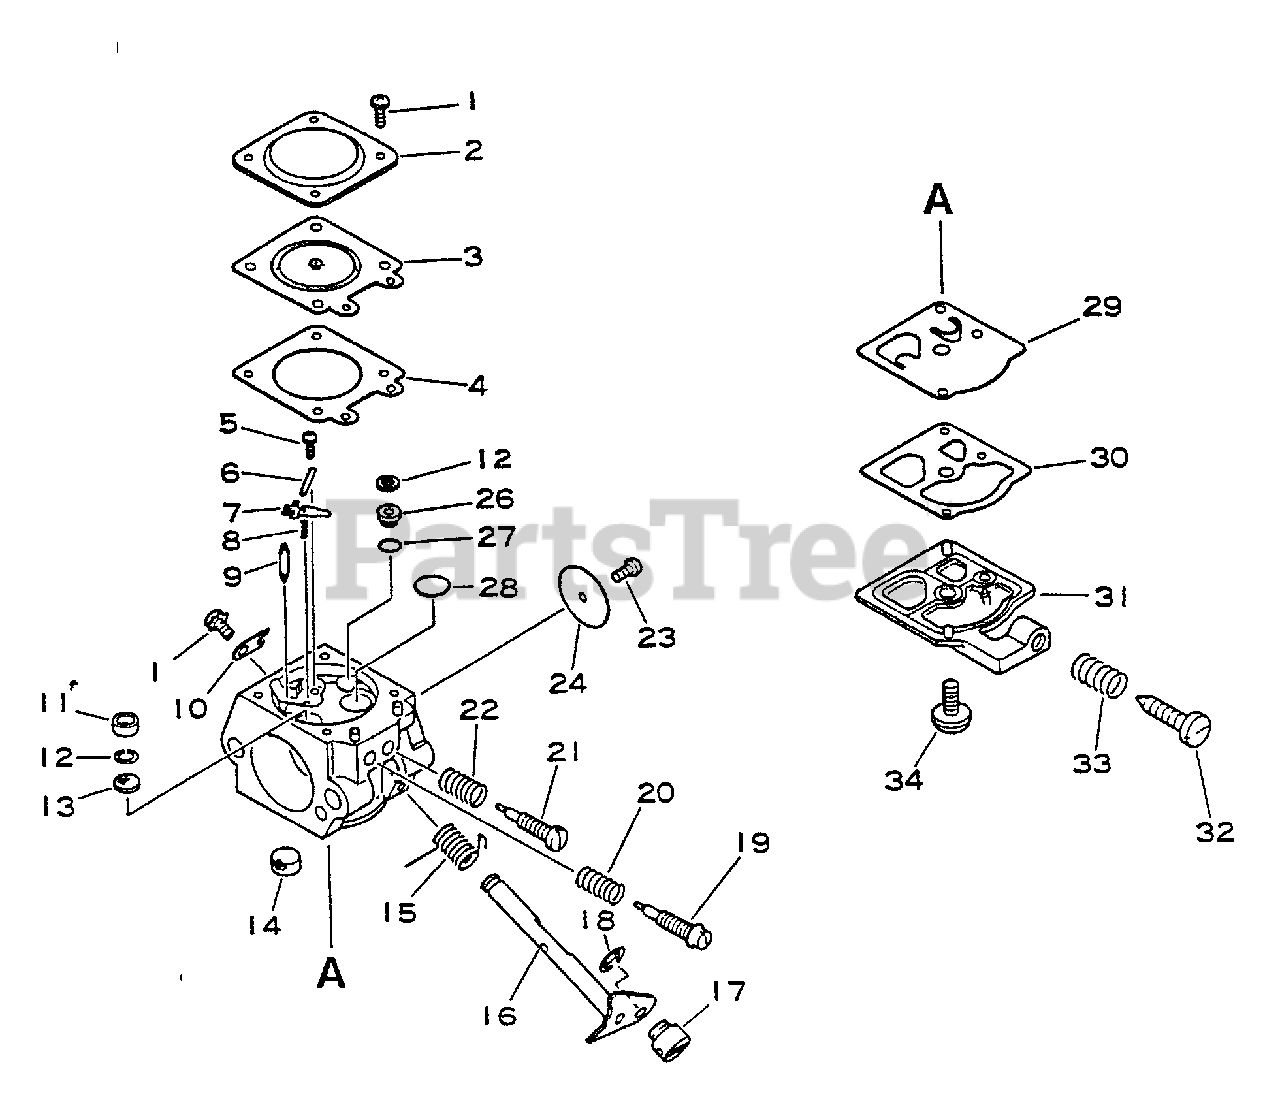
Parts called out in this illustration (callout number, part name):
1	SCREW
2	COVER, METERING
3	DIAPHRAGM, METERING
4	GASKET, METERING
5	SCREW
6	PIN, METERING LEVER
7	LEVER, METERING
8	SPRING, METERING LEVER
9	VALVE, INLET NEEDLE
10	CLIP, THROTTLE SHAFT
11	PLUG, WELCH
12	RING, RETAINING
13	SCREEN, SPARK ARRESTOR
14	STRAINER
15	SPRING, THROTTLE RETURN
16	SHAFT, THROTTLE
18	RING, RETAINING
19	NEEDLE - HIGH SPEED
20	SPRING, NEEDLE ADJUST
21	NEEDLE - LOW SPEED
22	SPRING, NEEDLE ADJUST
24	VALVE, THROTTLE
26	JET, MAIN
28	PLUG, WELCH
29	DIAPHRAGM, PUMP
30	GASKET, PUMP
31	COVER, PUMP
32	SCREW, IDLE ADJUST
33	SPRING, IDLE ADJUST
34	SCREW, PUMP COVER
